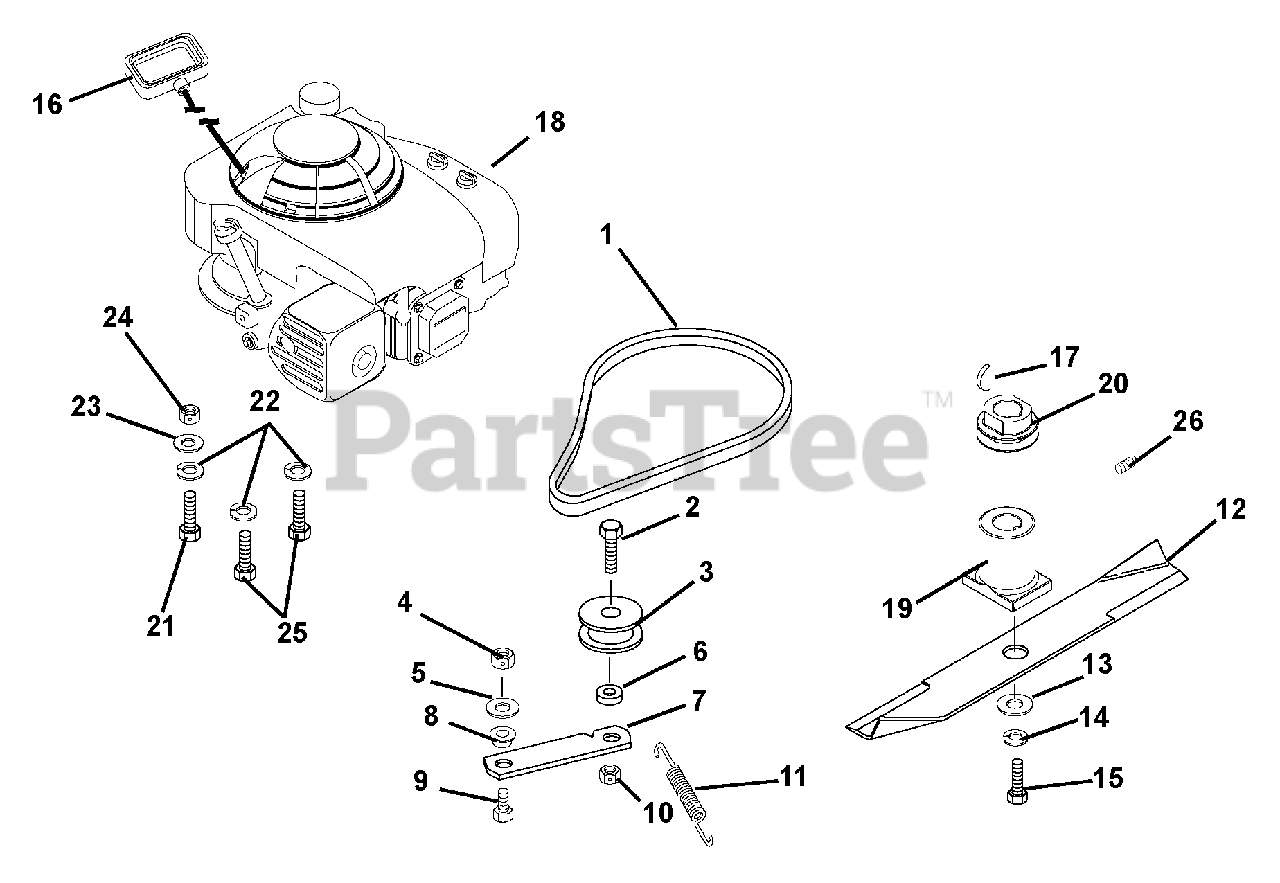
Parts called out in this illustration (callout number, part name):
1	V-Belt 3L Section
2	Bolt, Hex .44-14 x 1.50 Grade 5
3	Idler, Flat 1.75 x .47
4	Nut, Locking Center .31 -18
5	Washer, Flat Steel .344 x .688 x .065
6	Bushing, Sleeve .47 x .75 x .43
7	Idler Arm
8	Bushing, Flange .325 x .50 x .25 x 1.12
9	Bolt, Hex .31-18 x .75 Grade 5
10	Nut, Locking Center .44-14
11	Spring, Tension .043 x .44 x 3.31
12	Blade, 21" Mower
12	Blade, 21" Mower Tungsten
13	Washer, Flat Steel .390 x 1.50 x .125
14	Washer, Locking .38 x .094
15	Bolt, Hex .38-24 x 2.00 Grade 8
16	Recoil Start Handle
17	Key, Woodruff .156 x .625 x .25 SAE #6
18	Engine, Honda 5.5 HP OHV
19	Adapter, Blade Hub
20	Pulley, Steel Drive
21	Bolt, Hex .31-24 x 1.50 Grade 5
22	Washer, Locking .31 x .078 Regular
23	Washer, Flat Steel .344 x .688 x .065
24	Nut, Hex .312-24
25	Bolt Hex .31-24 x 1.00 Grade 5
26	Screw, Set .31-18 x .38 Socket Head
